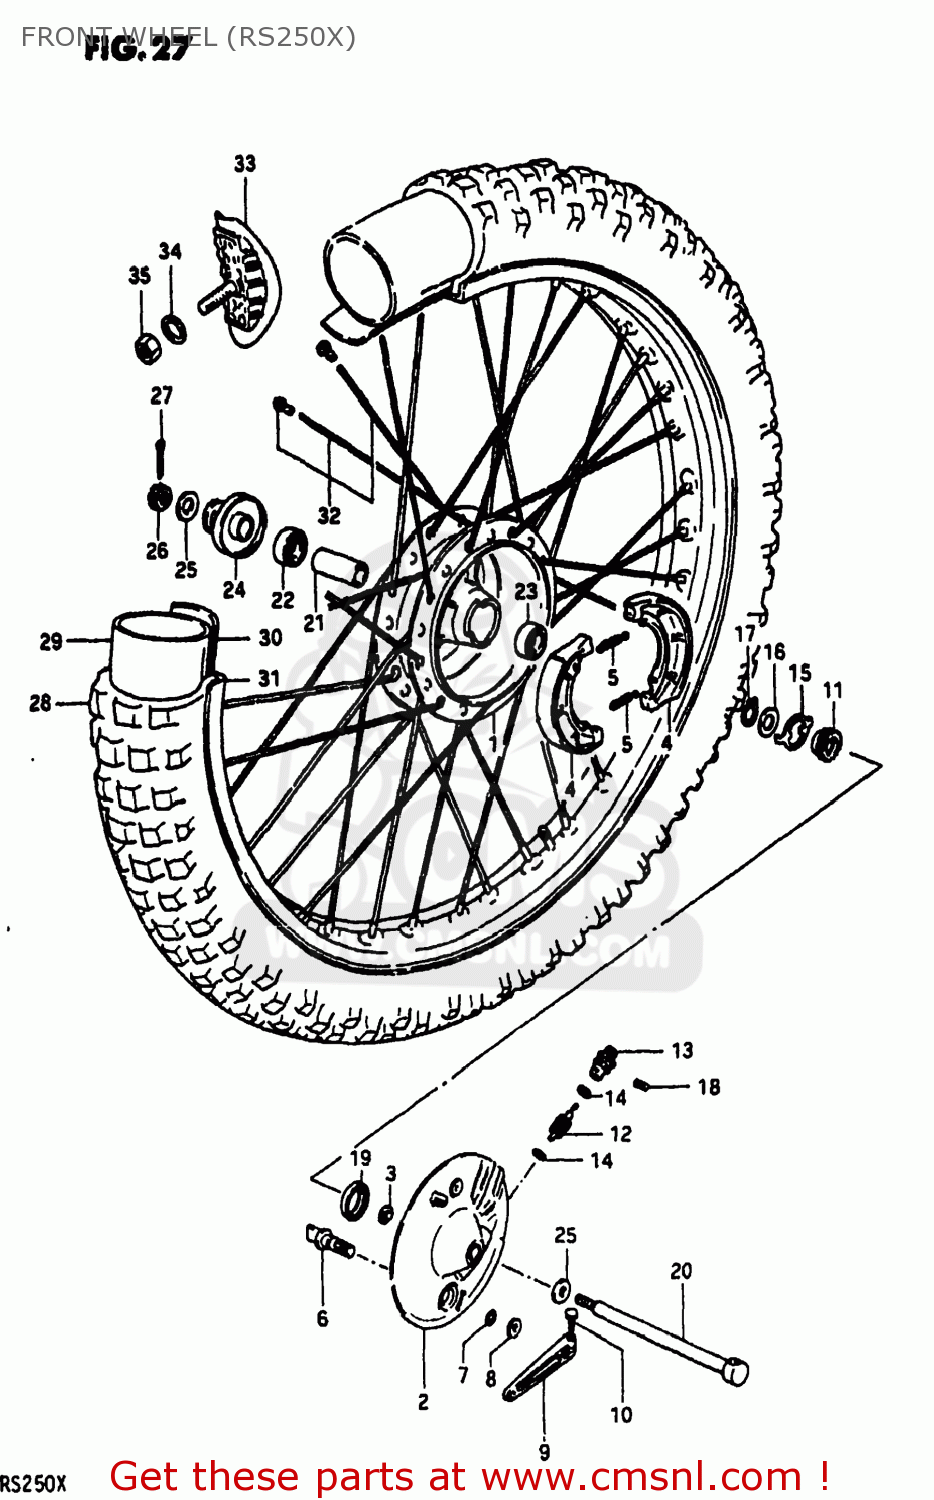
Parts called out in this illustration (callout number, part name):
1	HUB,FRONT
2	PANEL,FRONT HUB
3	BOSS
4	SHOE,BRAKE
5	SPRING(L:34)
6	CAM,FRONT BRAKE
7	O-RING (D:2.4 ID:13.8)
8	WASHER (14.5X22X1.6)
9	LEVER,FRONT BRAKE CAM
10	BOLT
11	GEAR,SPEEDOMETER
12	PINION,SPEEDOMETER
13	BUSH,METER GEAR OUTER
14	WASHER (5.1X9X0.4)
15	DRIVER,SPEEDOMETER GEAR
16	WASHER
17	CIRCLIP
18	SCREW
19	OIL SEAL (43X58X7)
20	AXLE,FRONT
21	SPACER (12.6X19X52)
22	BEARING, RH
23	BEARING
24	SPACER,FRONT AXLE,RIGHT
25	WASHER
26	NUT, REAR AXLE
27	COTTER PIN
28	TIRE,FRONT
29	TUBE,INNER
30	PROTECTOR,WHEEL,INNER
31	RIM,FRONT WHEEL
32	SPOKE SET,FRONT
33	STOPPER,BEAD
34	WASHER
35	NUT
